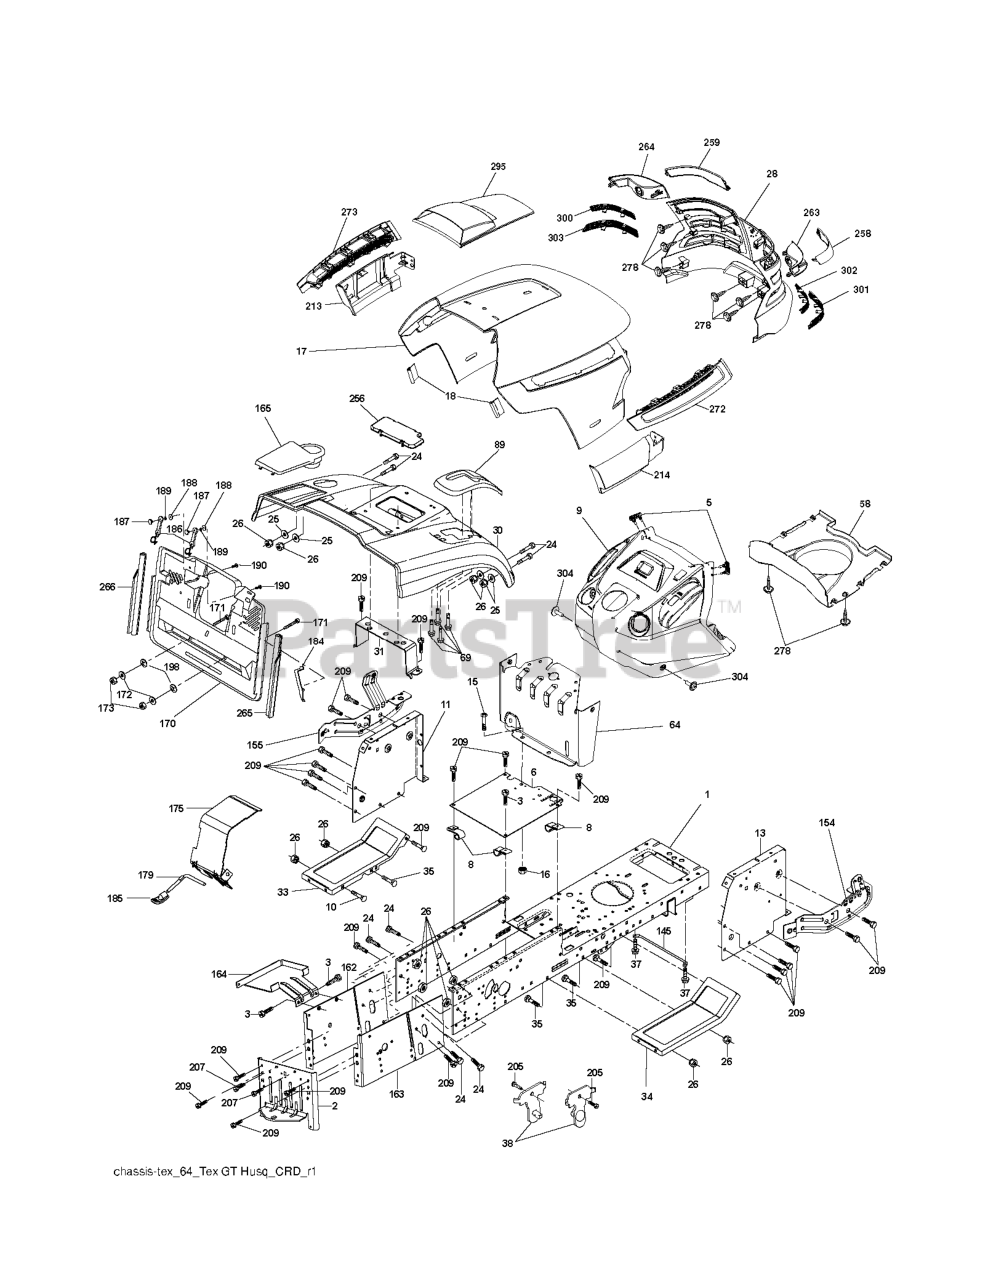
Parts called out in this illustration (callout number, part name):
2	DRAWBAR
3	SCREW 3/8-16X3/4
5	BUMPER DASH
6	PLATE
8	CLIP,INSULATOR
10	BOLT D
11	PANEL DASH LH
13	PANEL DASH RH
15	Screw, Machine, Truss Head 5/16-18 UNC x 3/4
16	NUT
17	HOOD
18	BUMPER.HOOD.TEX.HUSQVARNA
25	WASHER
26	NUT
28	GRILL.ASM.HUSQ.TG/CRD.W/TRIM
30	CONSOLE.CRD.AUTO.GRY
31	BRACKET SUPPORT FENDER
33	FOOTREST PNT LH
34	FOOTREST PNT RH
37	Screw 5/16-18 x 1/2 Hex, Self Tapping 5/16-18 x 1/2
38	BRACKET ASM PIVOT MOWER REAR
58	AIR.DUCT.HOOD.TEX.GT.HUSQ
69	SCREW.HI-LO.CONSOLE
89	CONSOLE.CRD.AUTO.GREY.2005
145	ROD.PIVOT.HOOD
162	BRACKET
163	BRACKET EXTEN CHASSIS RH CRD
165	RP.COVER.BATTERY.CRD.GREY
172	WASHER
175	DOOR TRAP
179	ROD PIVOT FBI
184	BRACKET.ACTUATOR.BAGGER.SRD
186	LATCH ASSY
187	WELDNUT
189	LOCKWASHER #10
190	SCREW
207	SCREW, 5/16-18 X 1/2
209	SCREW, 3/8-16X3/4
213	SKIRT.HOOD.SIDE.HUSQ.LH.GREY
214	SKIRT.HOOD.SIDE.HUSQ.RH.GREY
256	COVER FENDER CRD
258	LENS.RH.TEX.GT.HUSQ.CL
259	LENS.LH.TEX.GT.HUSQ.CL
263	BEZEL.RH.TEX.GT.HUSQ
264	BEZEL.LH.TEX.GT.HUSQ
265	SEALING
266	SEALING
272	VENT.SIDE.HOOD.HUSQ.RH.GREY
273	VENT.SIDE.HOOD.HUSQ.LH.GRAY
278	SCREW
295	VENT.ASM.TORPHD.HUSQGT.LOGO.CL
300	INSERT.HEX.GRILL.HUSQ.
301	INSERT.HEX.GRILL.HUSQ.GREY
302	INSERT.HEX.GRILL.HUSQ.
303	INSERT.HEX.GRILL.HUSQ.
304	SCREW 14-20 X 5/8
